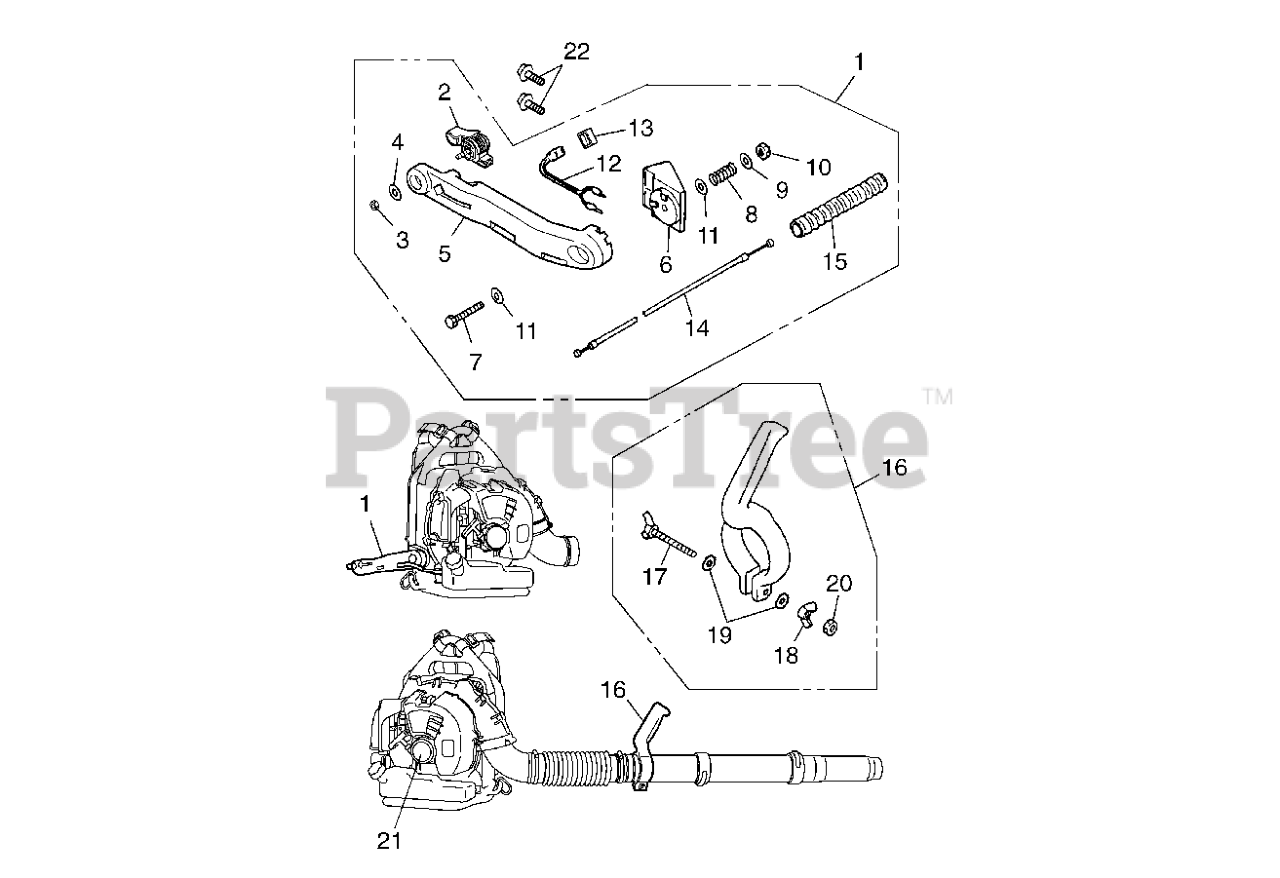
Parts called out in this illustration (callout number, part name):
1	HANDLE ASSY
4	WASHER
5	ARM
9	WASHER Z349525440
10	NUT 8488646000
12	KILL SWITCH
13	CAP SWITCH
14	CABLE COMP
16	GRIP ASSY
17	WING BOLT
18	WING NUT
19	WASHER
21	LABEL RECOIL 848L3W90C0
